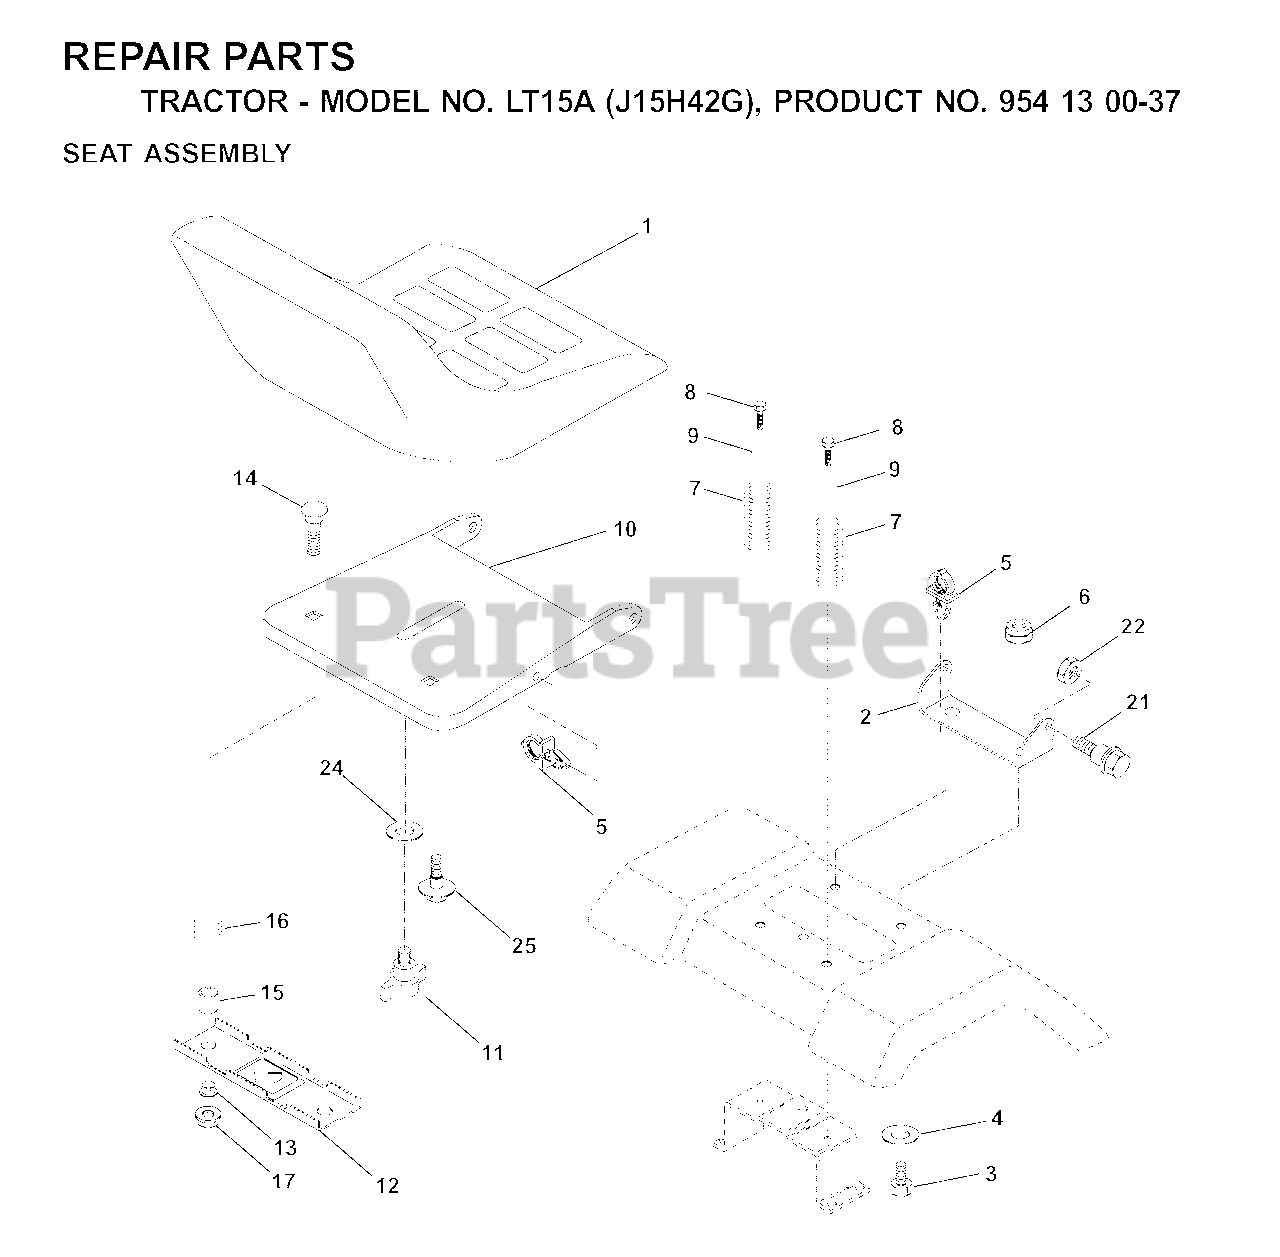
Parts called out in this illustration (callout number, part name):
2	SEAT PIVOT BRKT
4	WASHER PM
5	PUSH CLIP
6	NUT
7	SPRING COMPRESSION
8	SCREW 3/8-16X1
9	WASHER
10	PAN, SEAT
11	KNOB.SEAT.ADJ.WINGNUT
12	BRKT SWITCH
14	BOLT.ROUND.HEAD.SQUARE.NECK
15	SPACER SPLIT 28X.96
17	NUT T
21	BOLT.SHOULDER.5/16-18
22	NUT.71038.31-18.HEX.NYLOCK
25	BOLT,SHOULD
